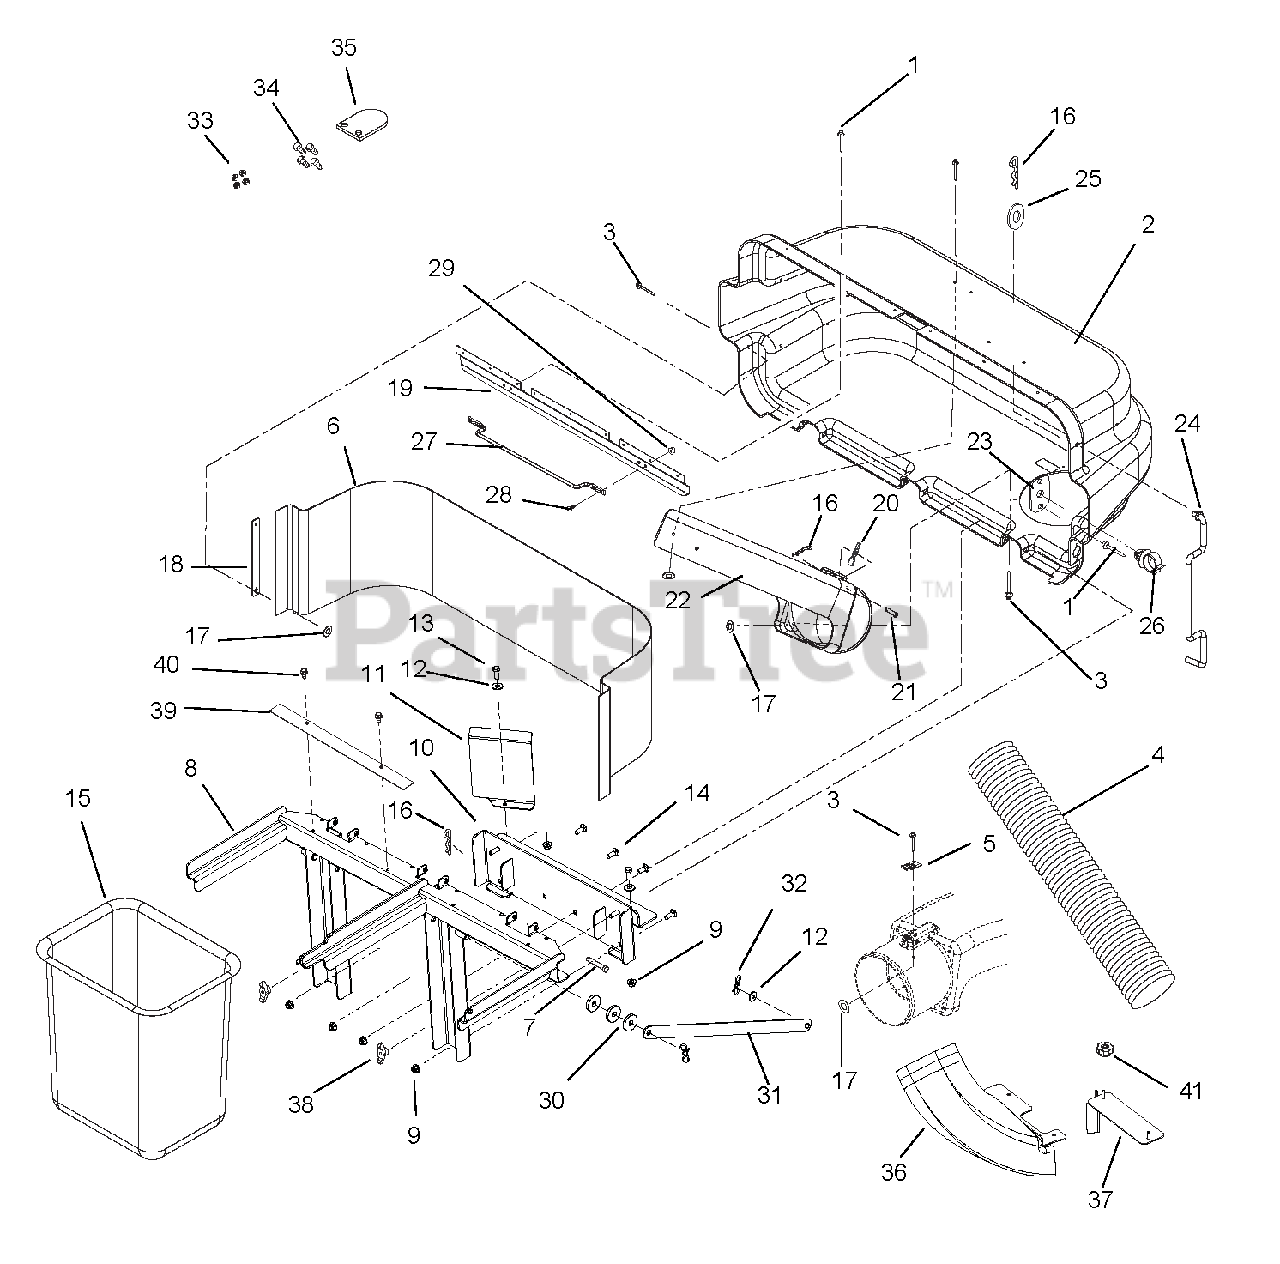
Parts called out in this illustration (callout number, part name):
1	RVT-POP .187X.402 DOME ST
2	BAGGER COVER W/DECAL
3	RVT-POP .187X.375
4	HOSE, FLEXIBLE-47"
5	THUMB LATCH
6	SCREEN, BAGGER
7	PIN-CLEV .371X3.25 YWZC
8	WMT, BAGGER FRAME
9	@NUT-LK-NYL-FLG .38-16 YWZC
10	WMT, MOUNTING PLATE
11	DEFLECTOR, MUFFLER
12	@WSHR-FL-STL.438X1.00X.083 YWZ
13	@BLT-HEX .38-16X1.00 GR5 YWZC
14	@BLT-RDHDSQNK .38-16X1.00 G5YZ
15	BAG, MESH ZOOM
16	PIN-HAIR, ENDRIES #25 YWZC
17	@WSHR-FL-STL.219X.50X.049 YWZC
18	STRAP,COVER
19	LATCH, BAGGER (MZ)
20	INDICATOR, FLOW
21	PIN-CLEV .309 X 1.625 YWZC
22	BOOT,UPPER
23	PLATE, ROD CLIP
24	PROP-ROD,BAGGER
25	@WSHR-FL-STL.406X.812X.065 YWZ
26	CLIP-.38
27	BAGGER HANDLE
28	@BLT-RDHDSQNK .25-20X.75 G5YZ
29	NUT-LUG .50-20 YWZC
30	WSHR-FL-STL .515X1.625X.250 YZ
31	PIN,BOW TIE LOCKING .091X1.875
32	WMT-STRAP, BAGGER
33	NUT .25-20 SPEED
34	BLT-HEX .31-24X.75 GR8 YWZC
35	VANE, BLADE
36	ASSY, 34" BAGGER BOOT
37	WELDMENT, 34" BAGGER MOUNT
38	NUT-WING .38-16
39	BRKT-BAGGER OVERLAP
40	@SCR-TAP .31-18X.50 HWH TR YWZ
41	KNOB-CLAMPING, .312-18 NYLOC
